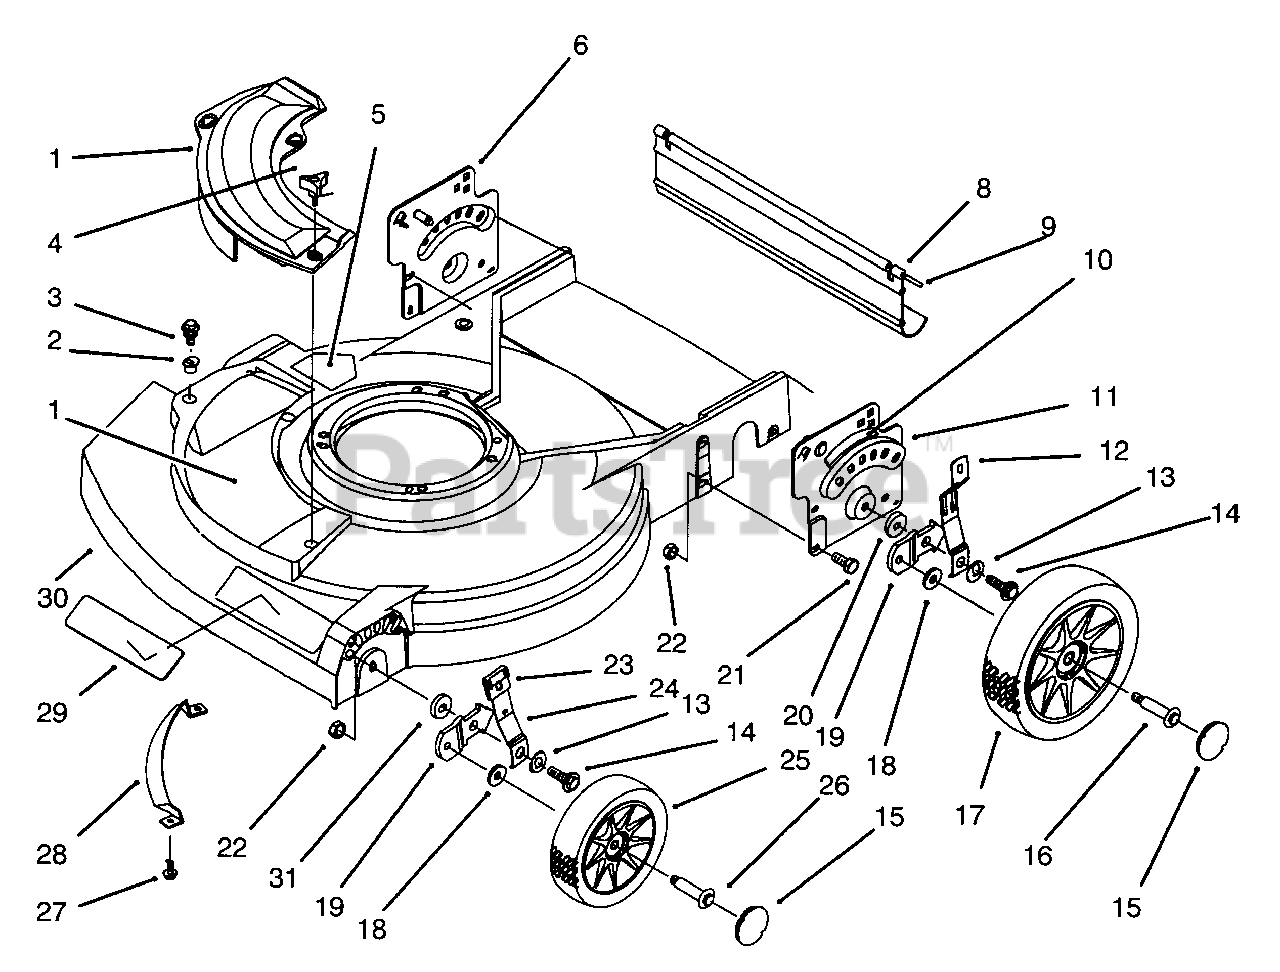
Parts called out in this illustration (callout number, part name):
1	Cover-Plate, Mulch
2	Grommet
3	Screw-Thread Forming
4	Knob
5	Decal-Danger (English)
6	Bracket-Handle, R.H.
8	Shield-Trailing
10	Decal-H.O.C. L.H.
11	Bracket-Handle, L.H.
12	Arm Assembly
13	Washer-Belleville
14	Bolt-Shoulder
16	Bolt-Wheel
17	Wheel Assembly 8"
18	Washer-Wheel Bolt
19	Bracket-H.O.C.
21	Screw
22	Nut-Lock
23	Knob Spring Arm
24	Arm Assembly
25	Wheel-6"
26	Bolt-Wheel
28	Bar-Toe
29	Applique
30	Housing-21" (Incl. Ref. #5 & 29)
